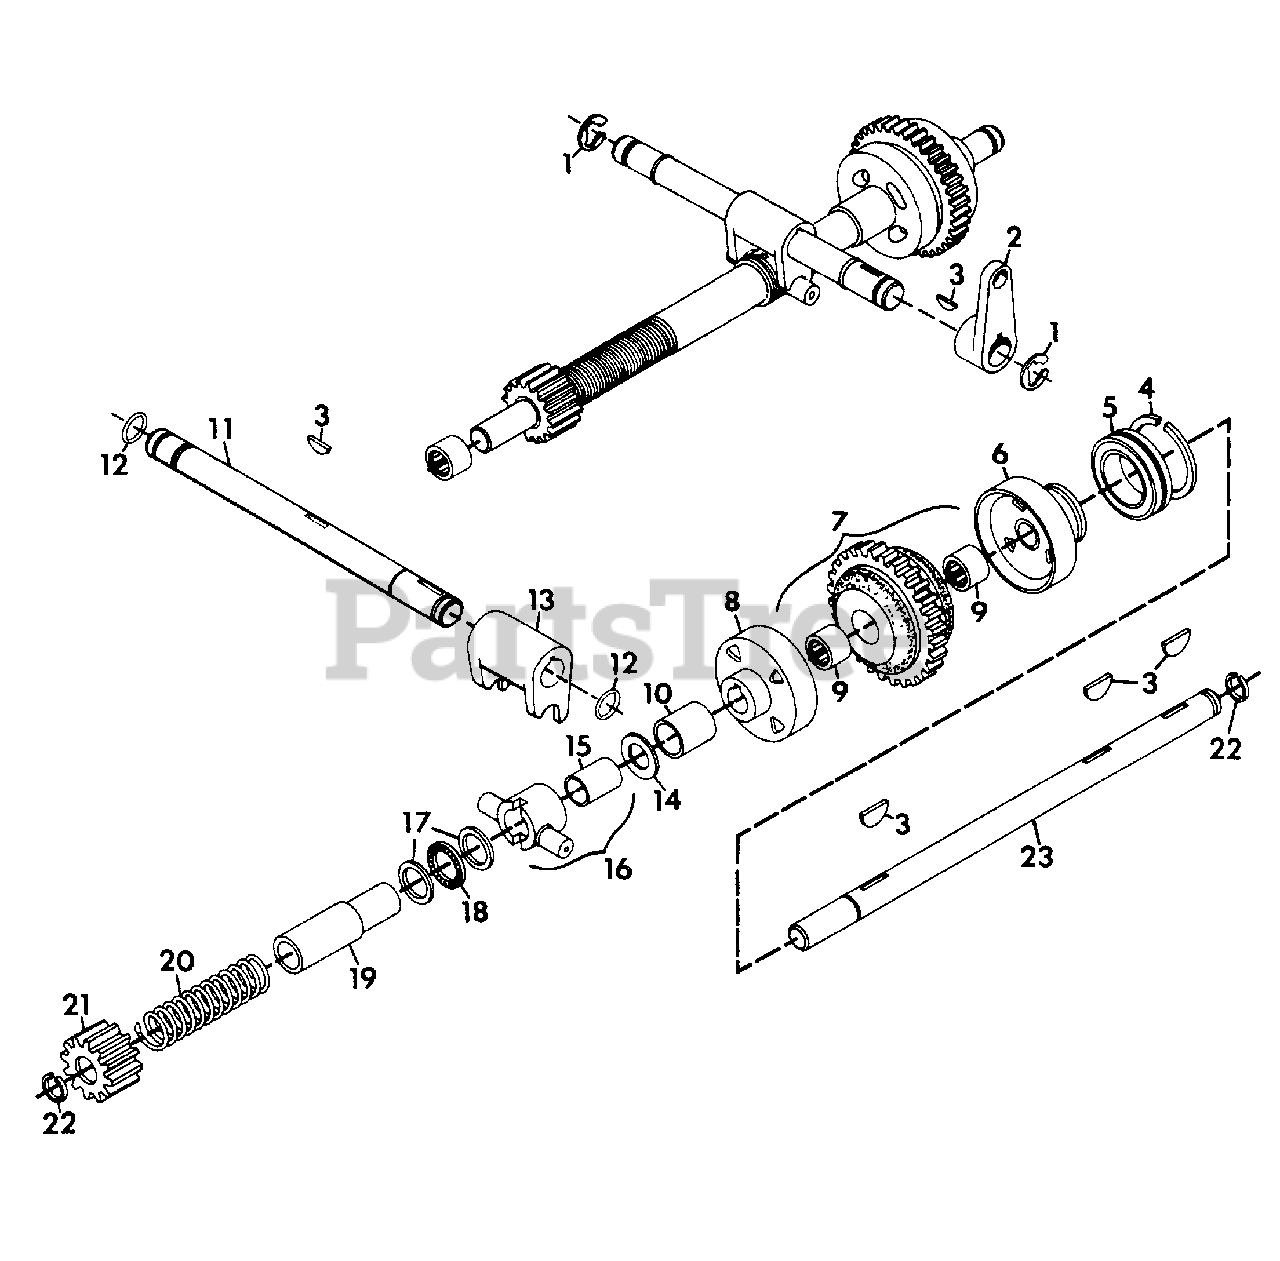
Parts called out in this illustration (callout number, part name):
1	E-RING, .750 SHAFT
2	LEVER, PTO
3	KEY, WOODRUFF .187X.750 HARD #9
4	RING, RETAINING 1.375 EATON 340-1
5	BEARING, BALL 1.378X2.440X.551
6	CUP, CLUTCH
7	ASSEMBLY, CLUTCH CONE BEARING
8	CUP, CLUTCH
9	BEARING, NEEDLE .750X1.00X.50
10	SPACER, PTO
11	SHAFT, PTO YOKE
12	O-RING, .625X.750X.060
13	YOKE, PTO
14	RACE, THRUST BEARING .752X1.240X.095
15	BUSHING
16	ASSEMBLY, SHIFTING COLLAR
17	BEARING, THRUST RACE 1.002X1.552X.093
18	BEARING, NEEDLE THRUST 1.002X1.552
19	THROW-OUT, PTO
20	SPRING, COMP. TYPE 5X1.50X200 RATE
21	GEAR, SPUR PTO 10 DP 22 TEETH X 1.200 STD.
22	RING, RETAINING .750 SHAFT
23	SHAFT, PTO CLUTCH
